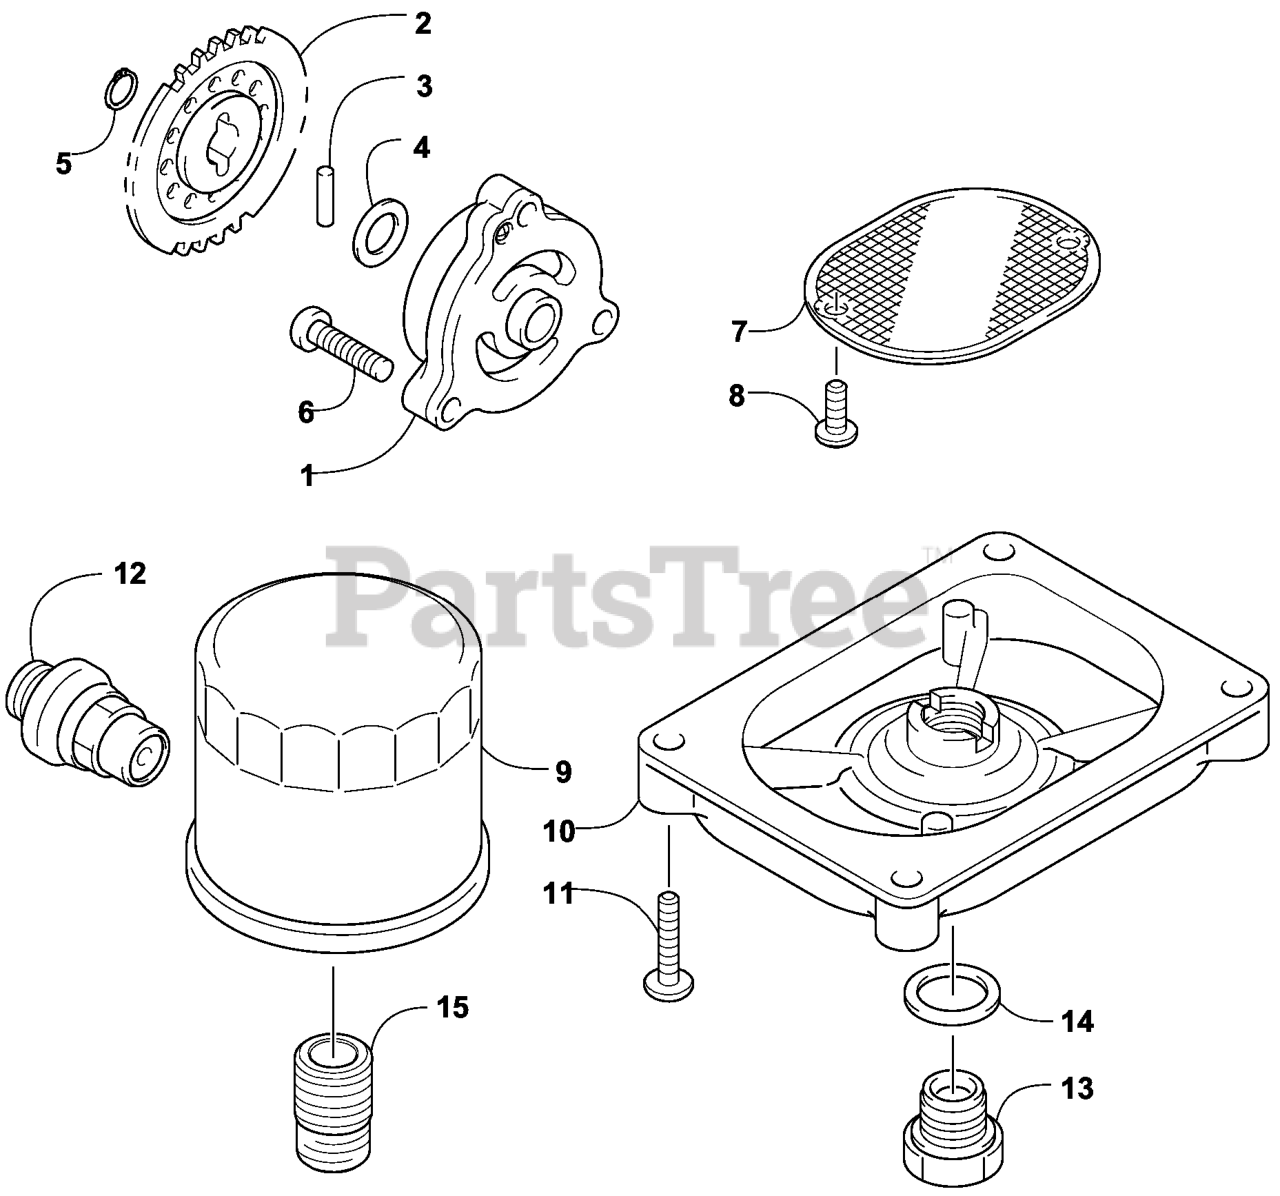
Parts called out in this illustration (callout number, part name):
1	PUMP-OIL LOW FLOW ASM
2	GEAR-DRIVEN, 29T
5	RING-RETAINING, EXTERNAL
6	SCREW-TSPH
8	SCREW-TSPH
9	FILTER,OIL
10	CAP-SUMP, OIL
11	SCREW-TSPNH
12	OIL RELIEF VALVE ASM
13	PLUG-DRAIN, MAGNETIC
14	GASKET-METAL, COMPRESSION
15	UNION-OIL FILTER
